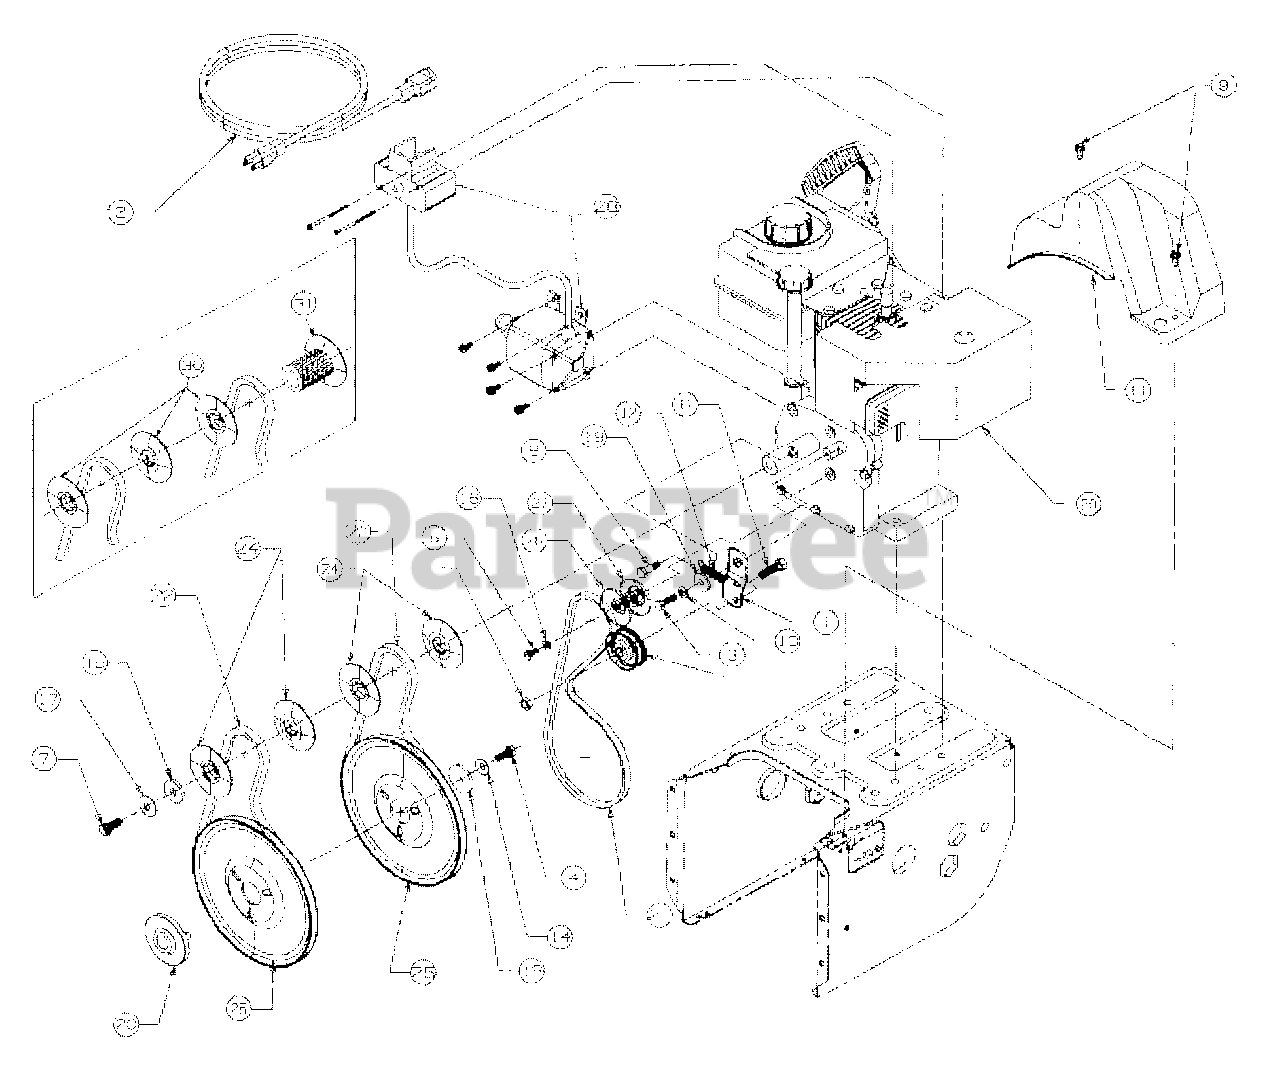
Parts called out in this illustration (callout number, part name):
3	Screw
4	Screw
5	Screw
6	Screw
7	Screw
8	Screw
9	Screw
10	Nut, Hex
11	Belt Cover
12	Spring
13	Washer-Lock
14	Washer-Bell
15	Flat Washer
16	Washer-Lock
17	Washer
18	Washer
19	Shoulder Spacer
20	Pulley Adapter
21	V-Belt
22	V-Belt
23	Idler, Flat
24	Pulley, Half (753F)
25	Pulley Auger
26	Pulley, Half
27	Pulley, Half
28	Starter (753F)
28	Starter (733E)
29	Engine
30	Pulley, Half (733E)
31	Pulley, Half (733E)
